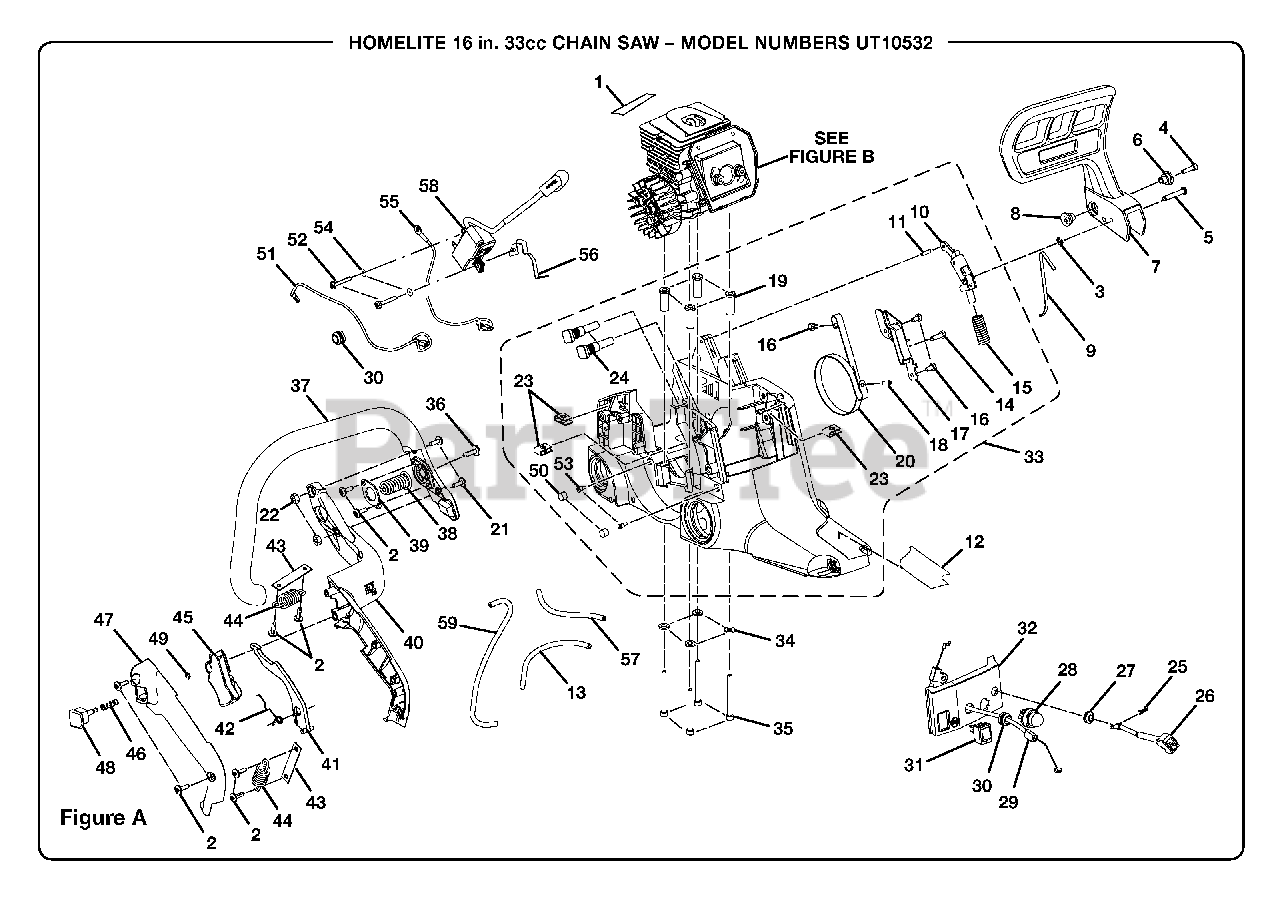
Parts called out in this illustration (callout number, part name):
1	Heat Reflector Tape
2	Screw (10-14 X 5/8 in. Torx Pan Hd.)
3	Retaining Ring
4	Screw (8-32 X 5/8 in. Hex Soc. Hd.)
5	Handguard Lever Pin
6	Pivot (Right Hand)
7	Handguard
8	Pivot (Left Hand)
10	Chain Brake Link Assembly
11	Roll Pin (Small)
12	On-board Label
13	Rubber Tubing (120 mm)
14	Screw (8-16 X 17 mm)
15	Spring
16	Screw (8-16 X 0.32 Pan Hd.)
17	Brake Band Cover
18	Roll Pin (Big)
19	Spacer Insert
20	Chain Brake Band Kit
21	Screw (10-24 X 19.5 mm)
22	Lock Nut (10-24)
23	Speed Nut ("U"-type)
24	Guide Bar Bolt
25	Spring Clip
26	Choke Rod
28	Primer Assembly
29	Throttle Cable
30	Split Grommet
31	Switch
32	Control Panel
33	Chassis Assembly
35	Screw (10-24 X 2 in. Soc. Cap Hd.)
36	Screw (10-24 X 5/8 in. Torx Hd.)
37	Front Handle
38	Upper Isolator Spring
39	Isolator Plate
40	Handle Support
41	Lockout Throttle
42	Torsion Spring
43	Isolator Limiter
44	Isolator Spring
47	Handle Cover
48	Throttle Lock Pin
49	Retaining Ring
51	Lead, Ignition Wire
52	Screw (9-15 x 1 in.)
53	Duck Bill Valve
55	Lead, Ground Wire
56	Slotware for Lead
57	Rubber Tubing (95 mm)
58	Ignition Module
59	Rubber Tubing (222 mm)
